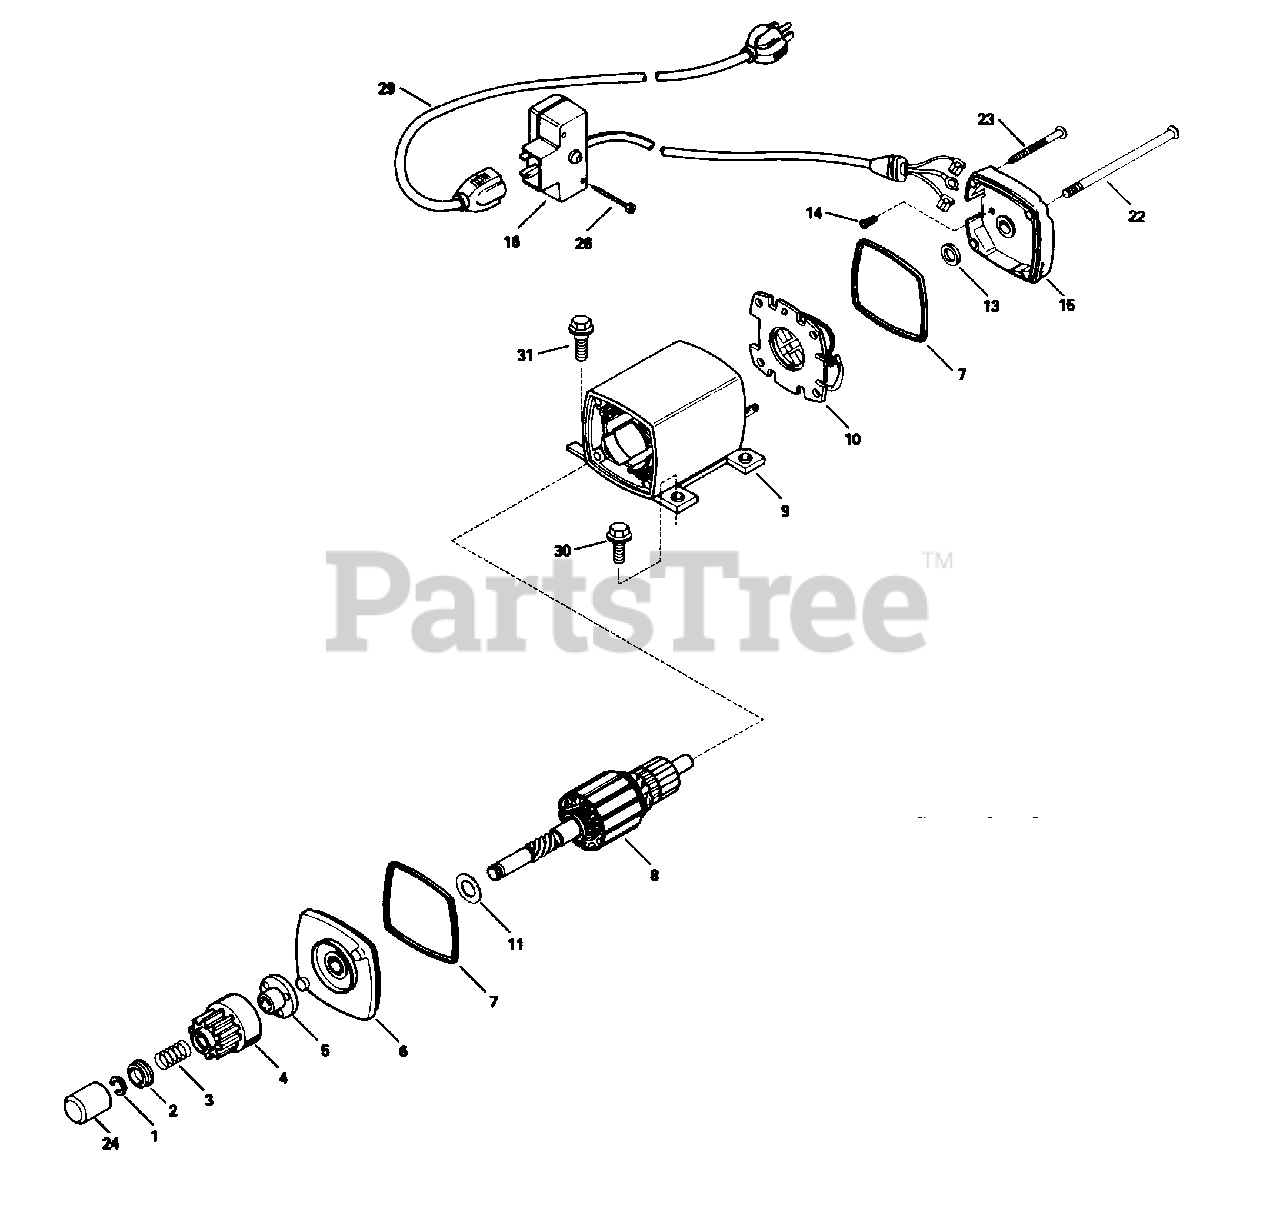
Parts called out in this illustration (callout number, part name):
1	Ring, Retainer
2	Retainer, Spring
3	Spring, Anti-drift
5	Nut & Retainer
6	Cap Ass'y., Drive End
9	Housing Ass'y
10	Card Ass'y., Brush
11	Washer, Thrust
13	Washer, Thrust
14	Screw, Ground
15	Cap Ass'y., Commutator End
16	Box Ass'y., Switch
22	Bolt, Case
23	Screw, Grounding
24	Cover, Dust
26	Screw, Hex Hd Self-Tap, 6-32 x 2-1/2
29	Cord, Extension (10'6")
30	Screw, T-30 Torx Hex Washer Hd. Sems, 1/4-20 x 1/2
31	Screw, Hex Hd. Shoulder, 1/4-20 x 1/2
